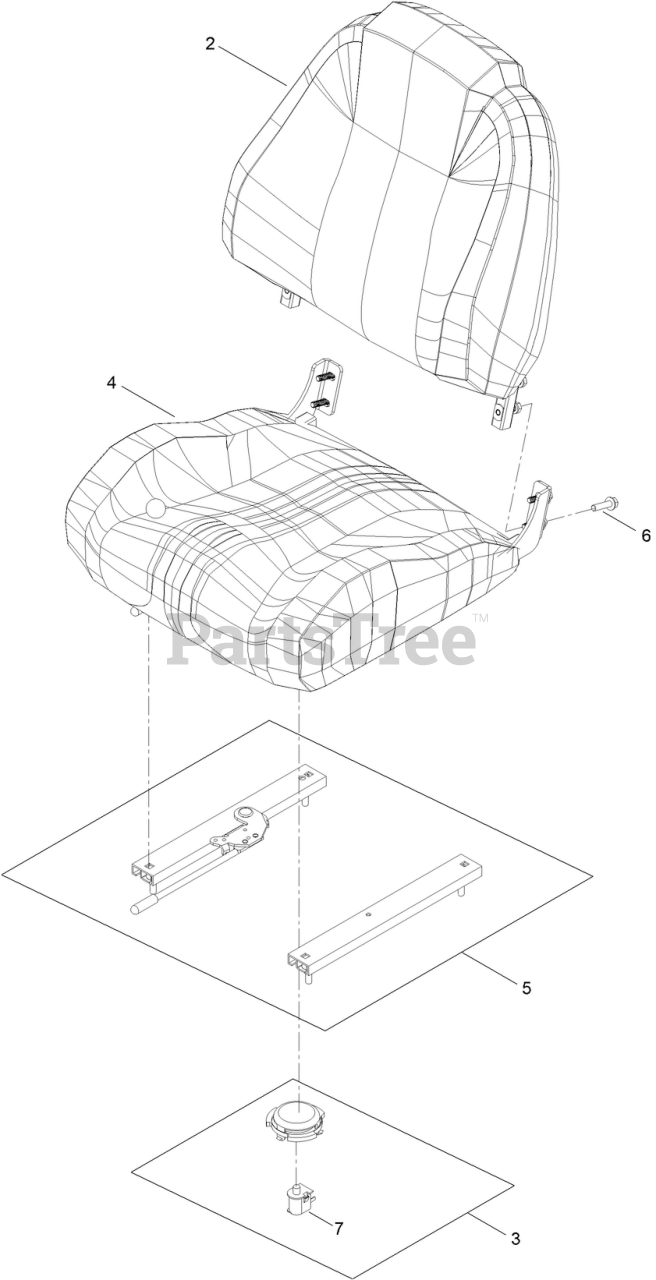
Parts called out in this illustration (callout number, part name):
2	TORO BACK COVER
3	SEAT SWITCH DELTA 6500-02 OPEN
4	TORO SEAT COVER
5	SLIDE ASM-SEAT
6	SCREW-HHF
7	SWITCH-BAIL
